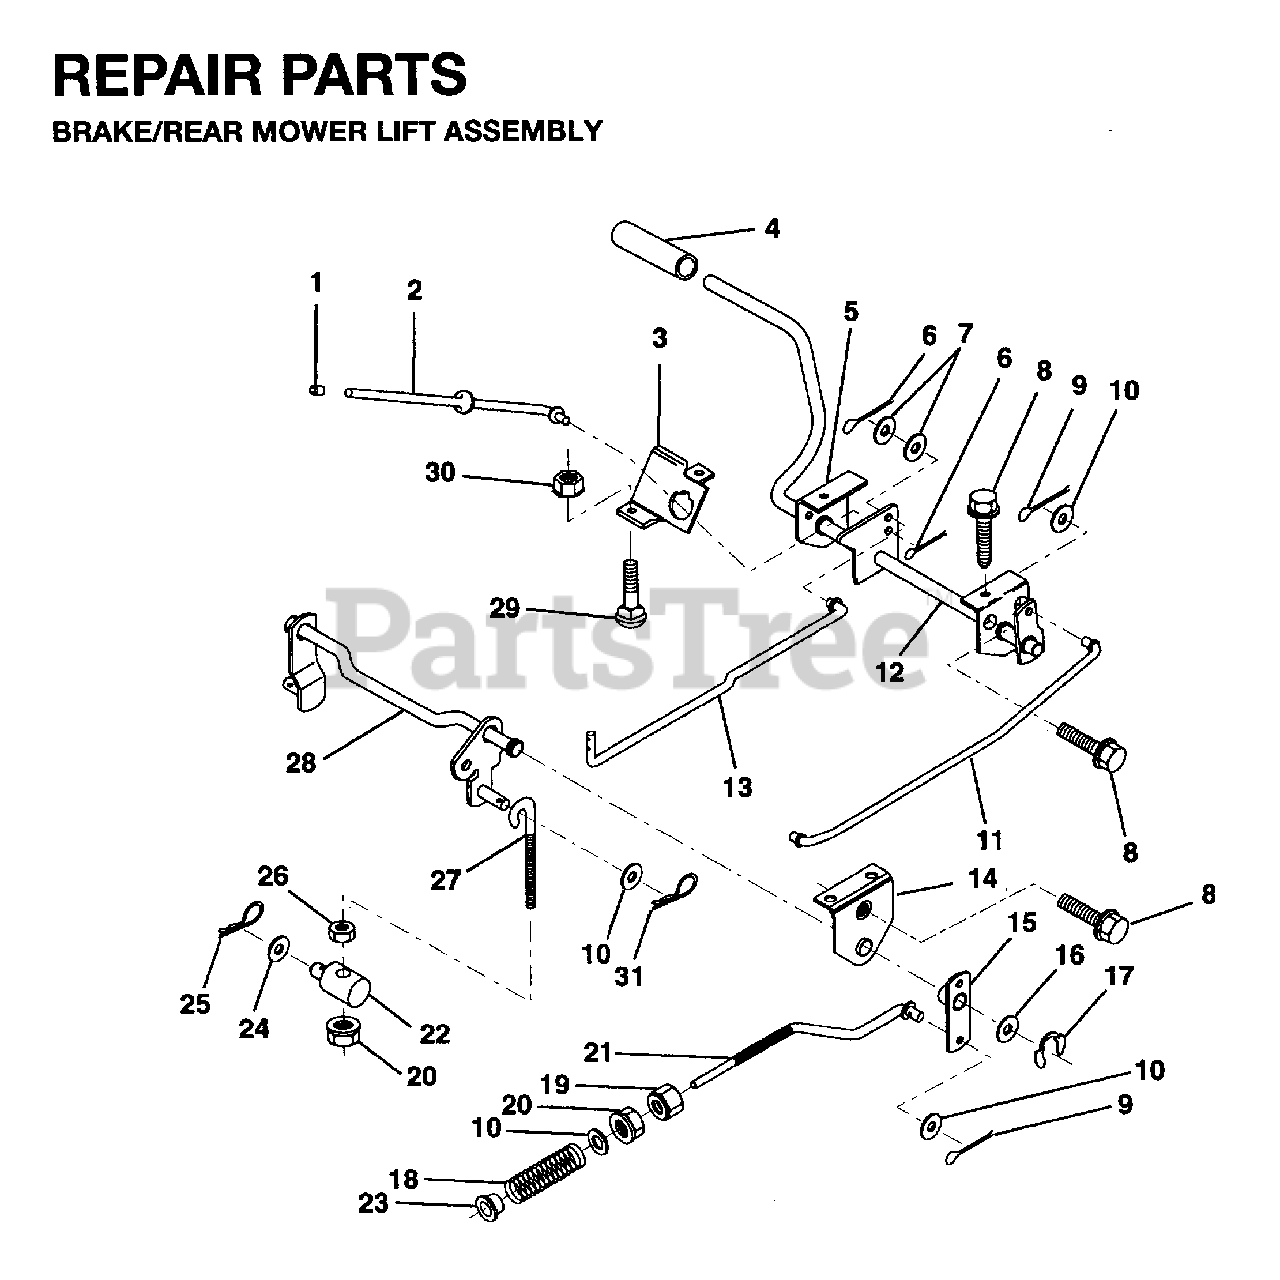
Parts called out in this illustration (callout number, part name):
1	PLUNGER CAP
2	ROD,PARK BRAKE
3	BRKT,PARK BRAKE
4	PEDAL COVER T
5	BRKT,CLU PEDAL LH
6	COTTER PIN
9	COTTER PIN
10	WASHER
11	ROD,FRT BRAKE
12	CLUTCH/BRAKE PEDAL ASSY
13	ROD,CLUTCH
14	BRKT,LIFT SHAFT
15	ARM, BRAKE ASMBLY
17	KLIP RING
18	SPRING ROD LT
19	NUT.HEX.3/8-16UNC
20	LOCKNUT
22	TRUNNION, LEFT
23	BUSHING.DRAGLINK
25	SPRING.RETAINER
26	LOCKNUT
27	LINK.MOWER.REAR
28	REAR MOWER LIFT ASSY
30	LOCKNUT
31	SPRING RETAINER
